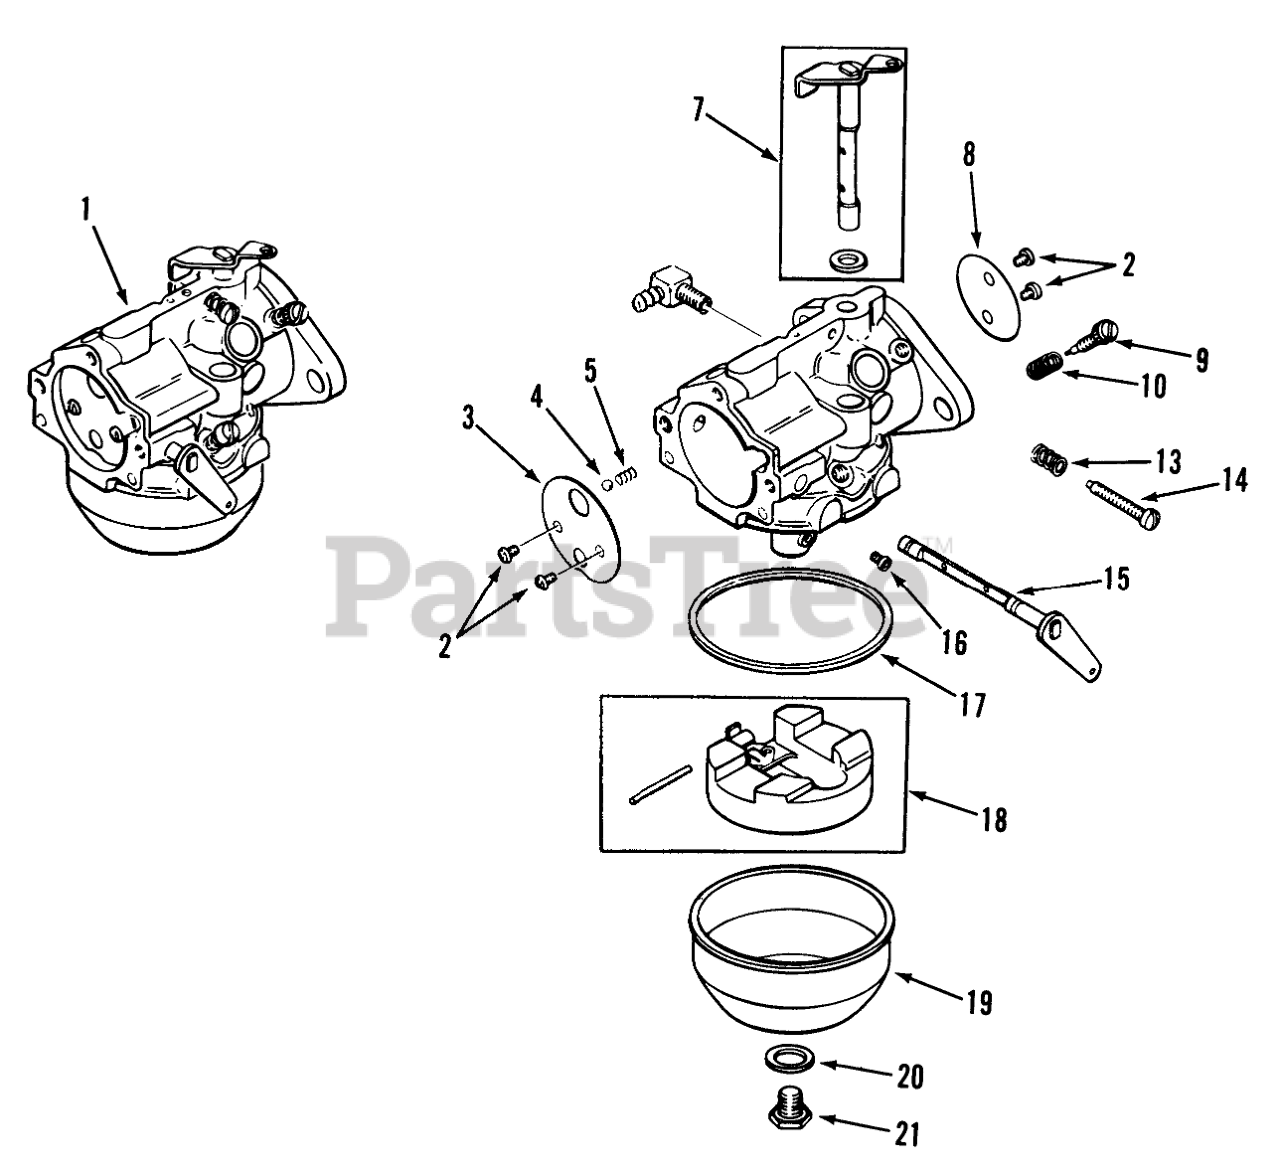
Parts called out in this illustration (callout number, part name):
1	KOHLER 47-853-20
2	KOHLER 25-086-27
3	KOHLER 47-146-08
4	KOHLER 25-194-01
5	KOHLER 25-089-03
7	KOHLER 457-144-21
8	KOHLER 25-146-02
9	KOHLER 25-368-01
10	KOHLER 25-089-02
13	KOHLER 25-089-04
14	KOHLER 25-086-26
15	KOHLER 47-090-38
16	KOHLER 47-337-02
17	KOHLER 25-041-04
18	KOHLER 25-757-09
19	KOHLER 25-104-01
20	KOHLER 25-041-03
21	KOHLER 25-100-05
